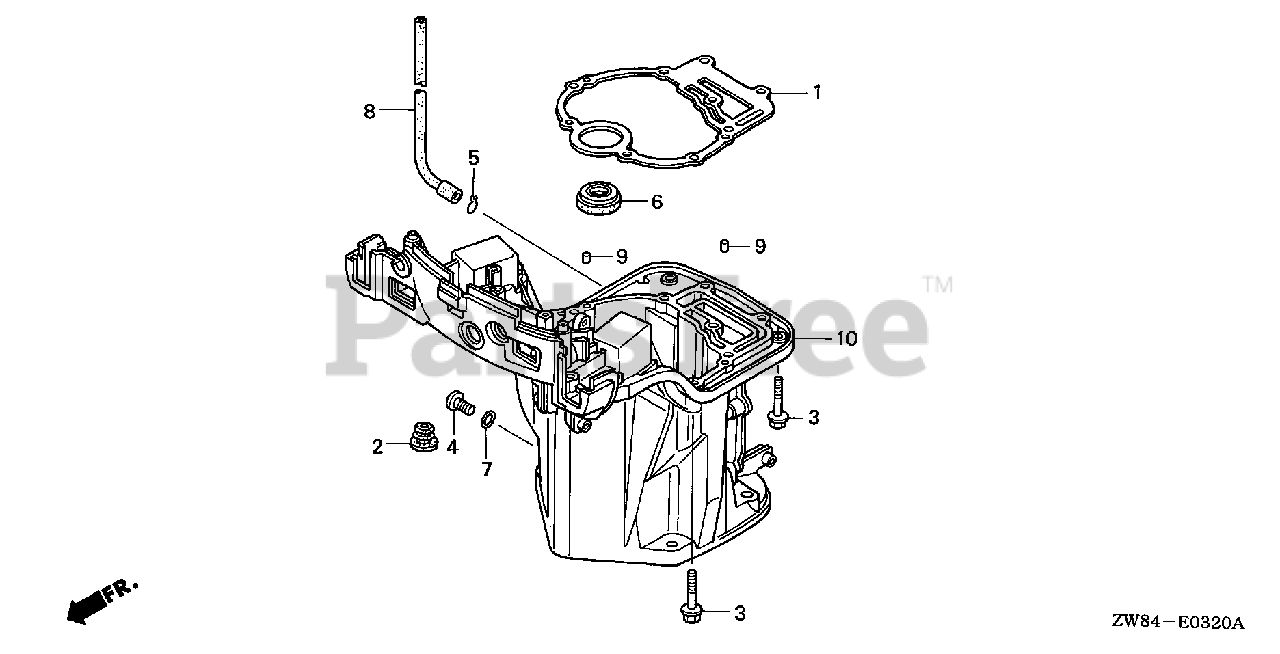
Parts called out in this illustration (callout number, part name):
1	GASKET, OIL PAN
2	GROMMET, WATER TUBE
3	BOLT, FLANGE (8X35)
4	BOLT, OIL CHECK
5	CLIP, TUBE (B10)
6	SEAL, WATER (13X28X7)
7	O-RING (5.5X1.5)
8	TUBE, WATER CHECK
9	PIN A, DOWEL (6X10)
10	CASE, OIL (000)
